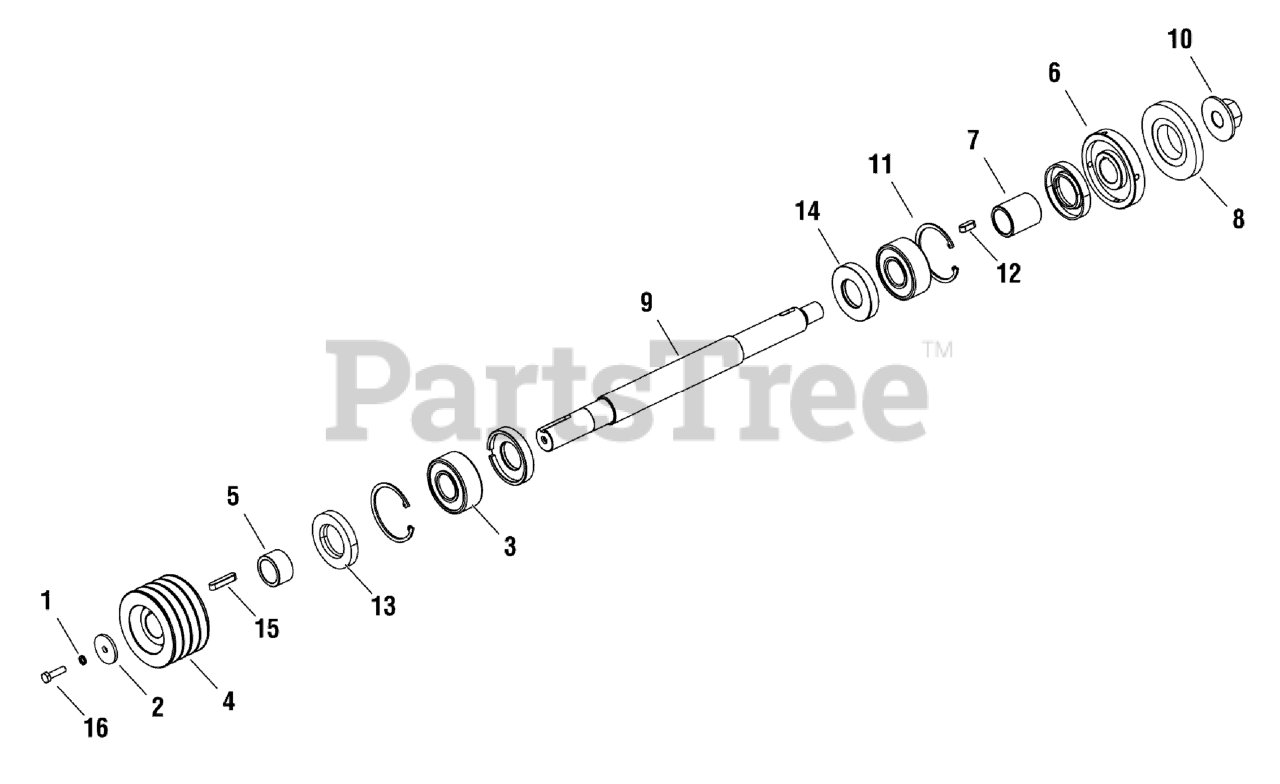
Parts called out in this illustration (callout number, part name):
1	WASHER, Spring, 8
2	WASHER, Flat, 8
3	BEARING
4	PULLEY, Big
5	BUSHING
6	PLATE, Blade Mounting
7	BUSHING
8	PLATE, Blade Pressing
9	SHAFT, Blade
10	NUT, Hex, Left, M24
11	CIRCLIP
13	OIL SEAL
14	SEAL RING
15	KEY, 10 x 45
16	BOLT, Hex, M8 x 30
